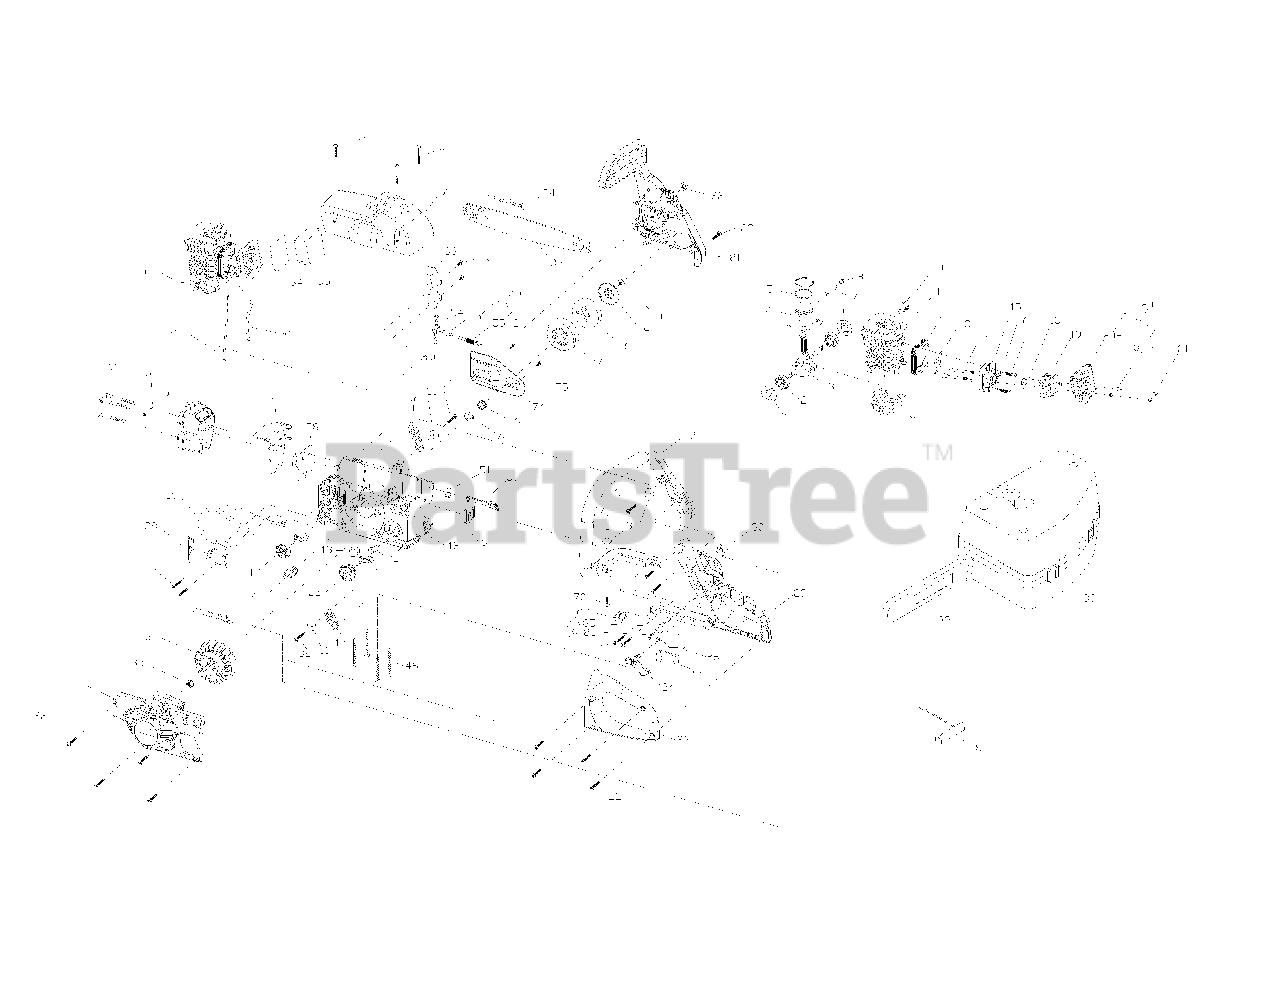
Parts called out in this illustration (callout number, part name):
1	CAP, BEARING
3	CRANK/ROD ASS'Y
5	RING, PISTON
6	ROLLER, PISTON
7	PIN, PISTON
9	CASE, CRANK
10	SPARK PLUG
12	RUBBER, ISOLATOR
15	ISOLATOR, CARBURETOR
16	SPRING WASHER
19	CARBURETOR
20	AIR FILTER ASS/Y
23	HANDLE, LEFT PART
24	TRIGGER, THROTTLE
25	TRIGGER, RELEASE
29	HANDLE, REAR
31	WASHER
33	HANDLE, FRONT
34	STARTER HOUSING ASS'Y
38	WIRE ASS'Y
39	IGNITION ASS'Y
40	CONDUCTIVE PLATE
41	OIL CAP ASS'Y
42	SPRING ASS'Y
44	FUEL CAP ASS'Y
48	HOUSING ASS'Y
49	HOLDER, CABLE
50	LEVER, CHOKE
51	HOLDER, CHOKE LEVEL
53	CONNECTOR
55	PUMP ASS'Y
59	MUFFLER ASS'Y
61	CABLE, THROTTLE
62	FUEL PIPE
63	WOODRUFF KEY
65	FILTER, AIR
66	SPIKED BUMPER
68	SCREW
70	SCREW
74	CAP, ANTI-DUST
76	SCREW
77	DRUM ASS'Y
78	CLUTCH ASS'Y
79	CAP, ANTI-DUST
81	BRAKE KIT ASS'Y
83	BAR, OREGON
88	BAR COVER
89	CARRY CASE
